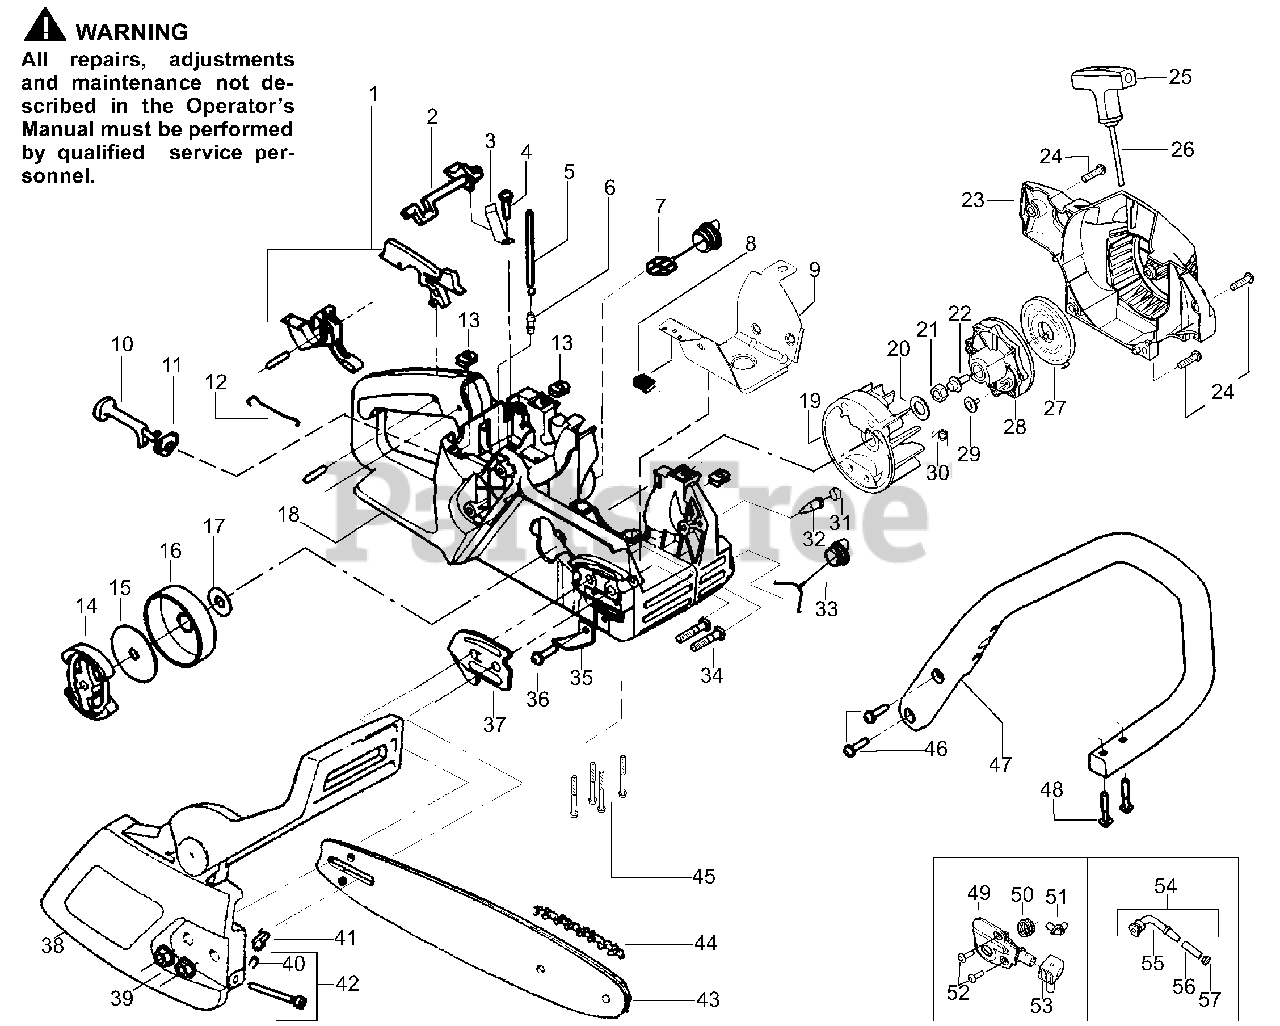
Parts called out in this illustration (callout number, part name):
1	Kit-Trigger & Lockout
2	Lever-Switch
3	Spring-Switch
5	Kit-Fuel Line (Large)
6	Fitting - Fuel line
7	Assy-Fuel Cap
8	Clip - "U"
9	Shield - Heat
10	Lever-Choke
11	Grommet-Choke lever
12	Wire-Throttle
13	Nut-Speed
14	Assy.-Clutch
15	Washer-Clutch
16	Assy-Drum W/brg.
17	Washer - Thrust
18	Kit - Chassis Assy.
19	Flywheel Ass'y.
20	Washer-Flywheel
21	Nut-Flywheel
23	Fan Housing
25	Handle-Starter
26	Kit-Rope
27	Spring-Starter
28	Pulley-Starter
30	Spring - Starter Dog
31	Plug - Bronze Vent
32	Check Valve
33	Assy-Oil Cap
34	Bolt - Bar
35	Chain Catcher
37	Plate-Bar Mounting
38	Assy.-Chain Brake
39	Nut-Bar Mounting
40	Retainer-Bar Adjust
41	Pin-Bar Adjust
42	Kit-Bar Adjust
44	Chain-12"
47	Handle-Front
49	Kit-Oil Pump
50	Gear-Worm Spring
51	Elbow-Oil Pickup
53	Seal Block
54	Assy-Oil-Pickup
55	Oiler Pickup
56	Oil Filter
57	Plug-Oil Filter
